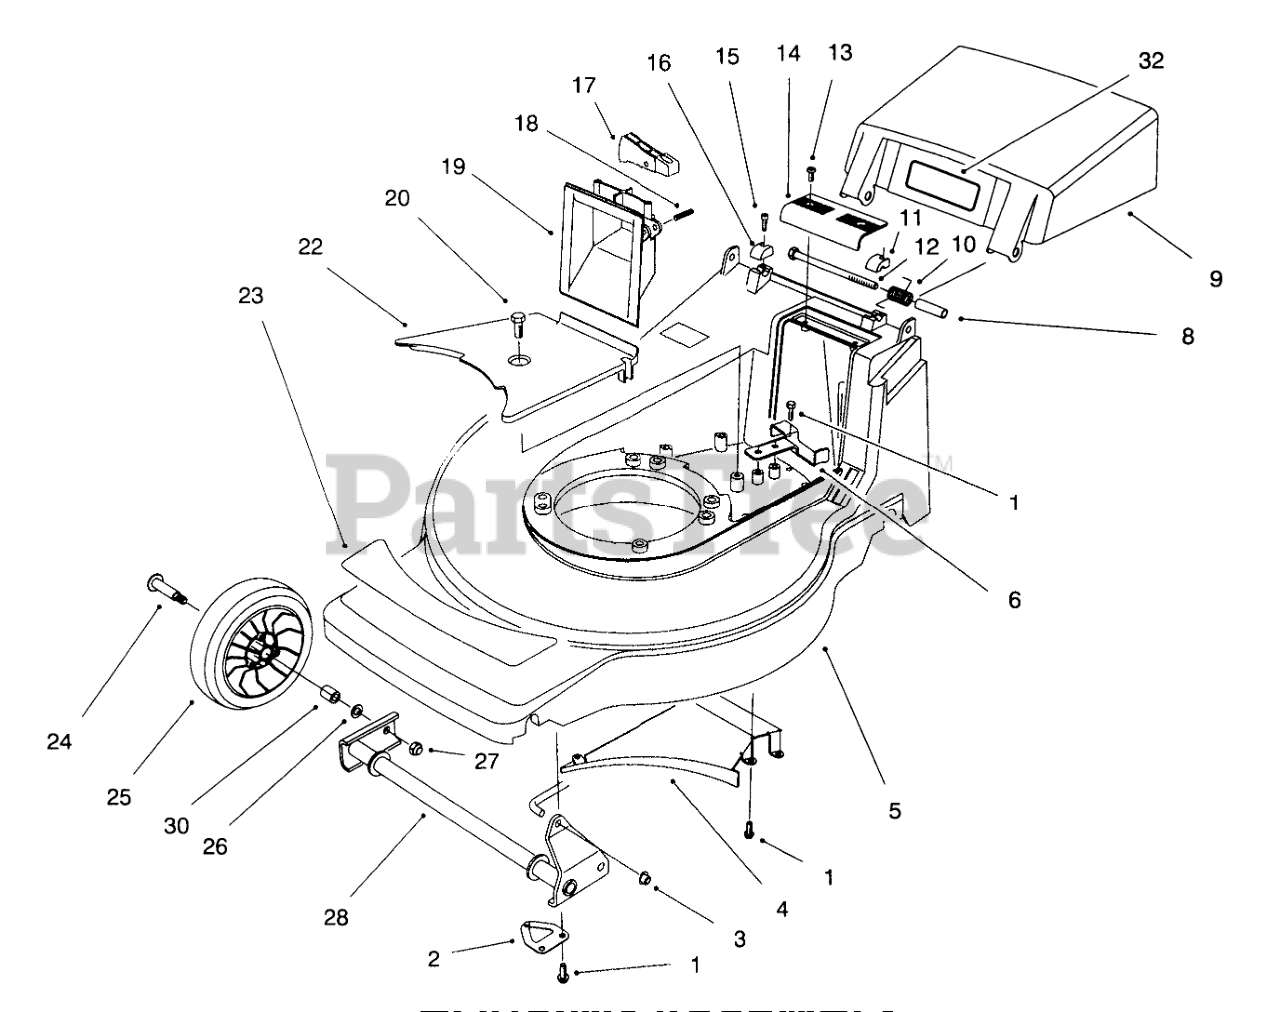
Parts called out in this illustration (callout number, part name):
1	Screw-Hex Hd. Tap
2	SHAFT RETAINER ASM
3	NUT-PUSH
4	Ramp-Discharge
5	Housing-48cm (Incl. Ref. #23)
6	REAR BELT GUIDE
8	SPACER-DOOR
9	Door-Discharge (Incl. Ref. #32)
10	SPRING-DOOR
11	CAP-HINGE BOLT, LH
12	SCREW-HH
13	SCREW-PPH, PLASTITE
14	GRIP-UPPER
15	SCREW-HSH
16	CAP-HINGE BOLT, RH
17	TRIGGER - HOC
18	PIN-SPIRAL
19	GRIP - LOWER
20	SCREW-HWHTF
22	BELT COVER
23	DECAL - DECK 48 CM
24	BOLT-WHEEL
25	Wheel & Tire Assembly (Incl. Ref. #30)
26	WASHER
27	NUT-HEX
28	FRONT PIVOT WA
30	BUSHING
32	DECAL-DANGER
